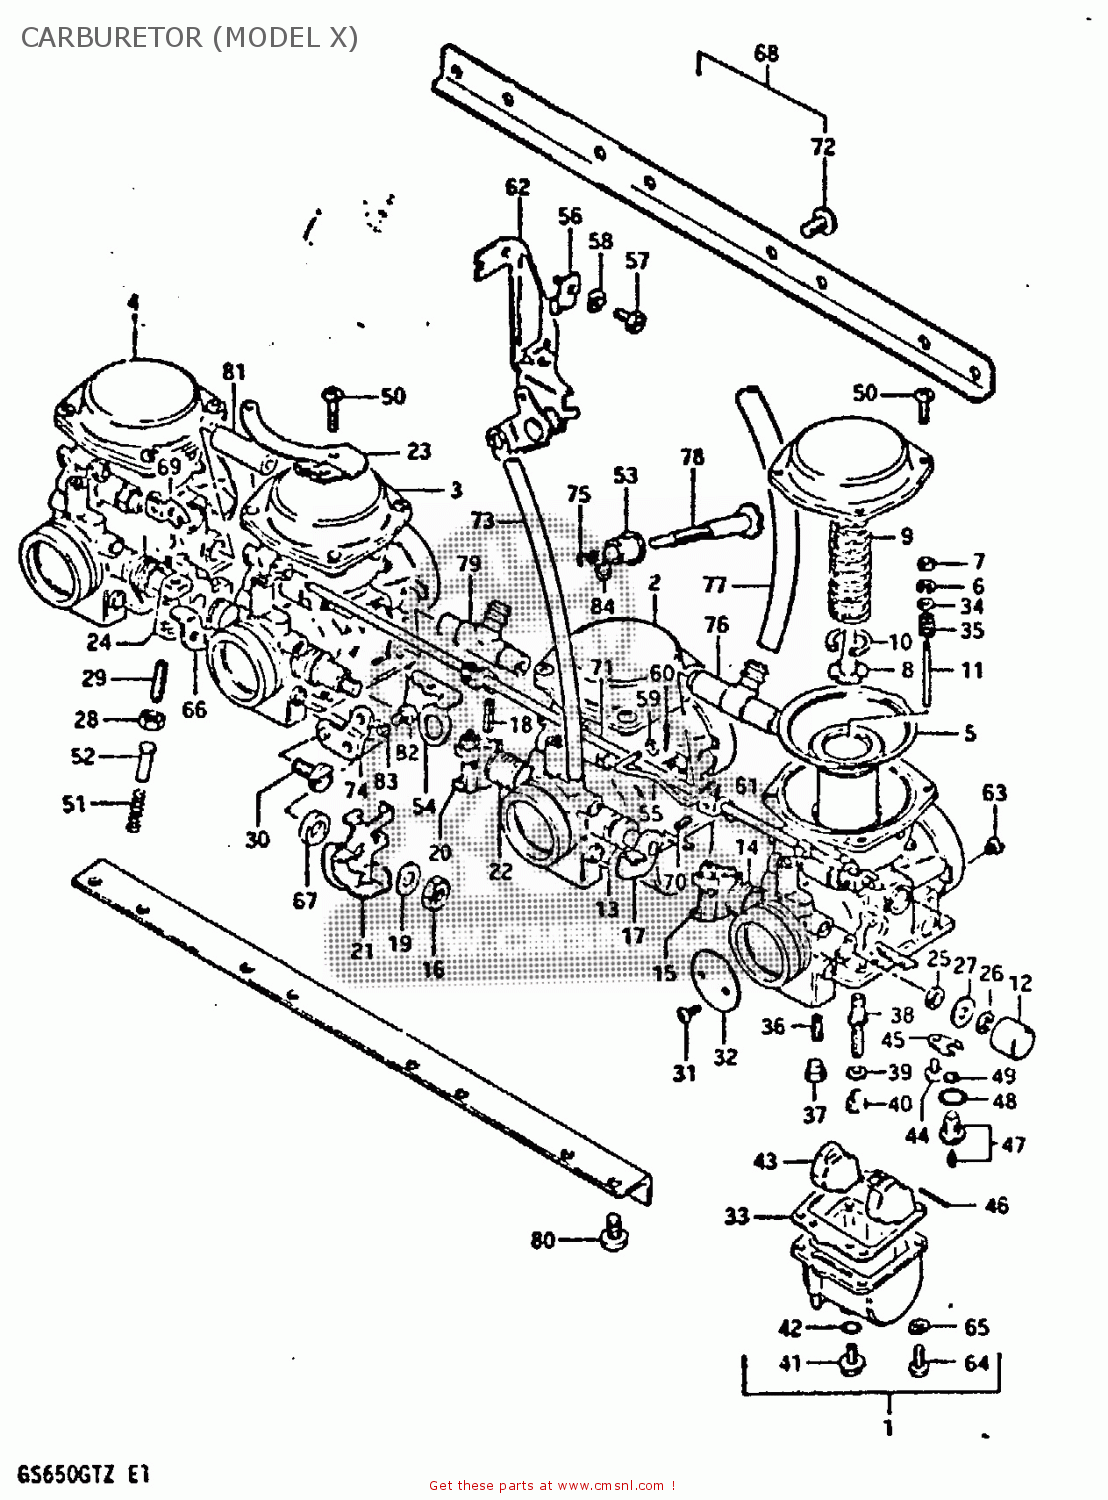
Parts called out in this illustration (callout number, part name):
1	CARBURETOR ASSY, LH
2	CARBURETOR ASSY, ML
3	CARBURETOR ASSY, MR
4	CARBURETOR ASSY, RH
5	DIAPHRAGM
6	CLIP,NEEDLE
7	RING
8	HOLDER,GUIDE
9	SPRING
10	E RING
11	NEEDLE, JET (5C41-3)
12	CAP
13	GASKET,THROTTLE SHAFT (NAS)
14	SPRING,THROTTLE SHAFT
15	SHAFT,THROTTLE
16	NUT 8MM
17	SHAFT,THROTTLE
18	PIN,THROTTLE SHAFT
19	WASHER
20	LEVER,THROTTLE SHAFT
21	LEVER ASSEMBLY,THROTTLE
22	SPRING,THROTTLE SHAFT
23	BRACKET
24	SHAFT,THROTTLE
25	SEAL
26	E RING
27	GASKET,THROTTLE SHAFT (NAS)
28	NUT
29	SCREW
30	SCREW
31	SCREW
32	VALVE,THROTTLE (BUTTERFLY)
33	GASKET,FLOAT CHAMBER (NAS)
34	WASHER
35	SPRING
36	JET, PILOT (42.5)
37	PLUG,NEEDLE JET
38	JET, NEEDLE (Y-7)
39	WASHER,NEEDLE NOZZLE
40	JET, MAIN
41	PLUG,DRAIN
42	GASKET (NAS)
43	FLOAT
44	SCREW 4X6
45	PLATE,NEEDLE VALVE FITING
46	PIN,FLOAT
47	VALVE ASSEMBLY,NEEDLE
48	O-RING,NEEDLE VALVE
49	FILTER
50	SCREW
51	SPRING,THROTTLE SCREW
52	PIN,THROTTLE LEVER
53	BUSH
54	BRACKET,THROTTLE ADJUST
55	ROD,STARTER LEVER
56	BRACKET,STARTER
57	BOLT
58	LOCK WASHER
59	SEAT,SPRING
60	PIN
61	LEVER ASSY
62	BRACKET
63	JET,AIR(140)
64	SCREW
65	LOCK WASHER
66	SHAFT,THROTTLE
67	WASHER
68	CARBURETOR ASSEMBLY
69	LEVER
70	SCREW
71	SHAFT,STARTER
72	SCREW
73	HOSE
74	BRACKET,THROTTLE ADJUST
75	SPRING
76	NIPPLE
77	HOSE
78	SCREW
79	NIPPLE,CARBURETOR
80	SCREW 6X12
81	NIPPLE
82	SCREW
83	LOCK WASHER
84	WASHER
